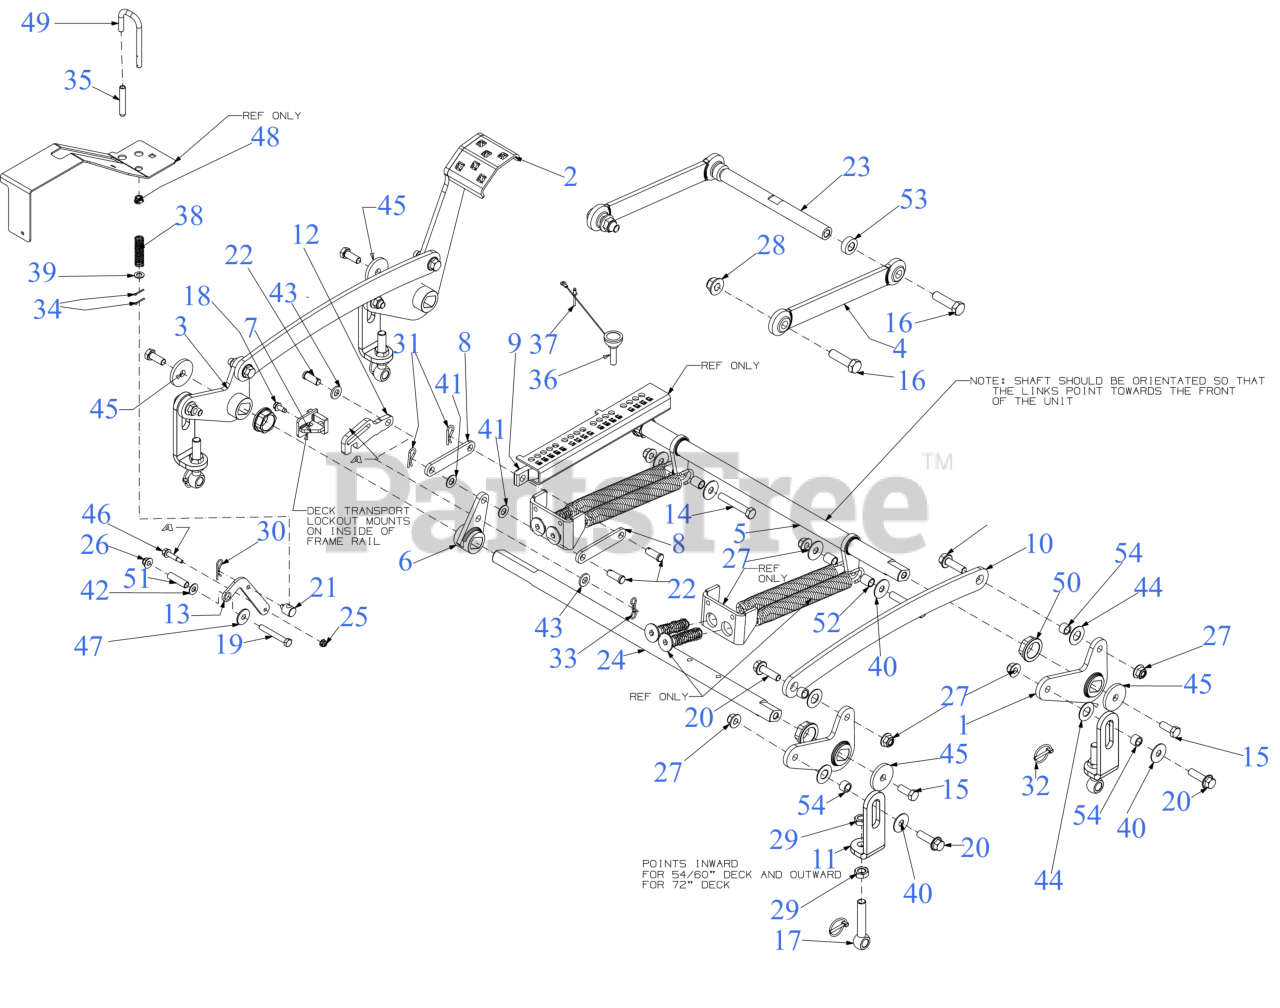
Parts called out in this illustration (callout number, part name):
5	FRONT DECK LIFT SHAFT
6	DECK LIFT HUB ASSEMBLY (LH)
7	LIFT LOCK MOUNT
8	DECK LIFT INDEX LINK
9	LIFT INDEX SLIDER ARM
12	LOCK LATCH BRACKET
13	PIVOT LOCKOUT LINK
14	SCREW-HEX 1/2-13 x 3.00
15	SCREW 1/2-13 x 1.25 GR5
16	SCREW 5/8-11 x 2.25 GR5
17	EYE BOLT 5/8-11 x 3.63
18	SCREW 5/16-18 x .750
19	SCREW 3/8-16 x 2.75 GR5
20	FLANGE BOLT 1/2-13:1.75:GR5
21	BRAKE ROD FERRULE
22	CLEVIS PIN .500 x 1.25
23	FRONT LIFT SHAFT
24	LIFT SHAFT 1.25 DIA
25	FLANGE LOCK NUT
28	FLANGE LOCK NUT
30	INTERNAL COTTER PIN
31	COTTER PIN
32	LYNCH PIN .1875
33	PIN:COTTER
34	COTTER PIN 3/32
36	DECK LIFT KNOB
37	FULL TUBULAR RIVET
38	COMPRESSION SPRING .656 ODX 2.445"
39	FLAT WASHER
40	WASHER .51 x 1.5 x .07
41	FLAT WASHER .510 x .995
42	FLAT WASHER
43	FLAT WASHER .510 x 1.000 x .125
44	FLAT WASHER
45	FLAT WASHER .53"x2.125"x.25"
46	SHOULDER SCREW
47	SHOULDER SPACER
48	BUSHING .380 ID
49	DECK LOCK OUT ROD
50	FLANGE BEARING
52	SPACER 0.535 x 0.68 x 0.83
53	SPACER .635X1.25X.445
